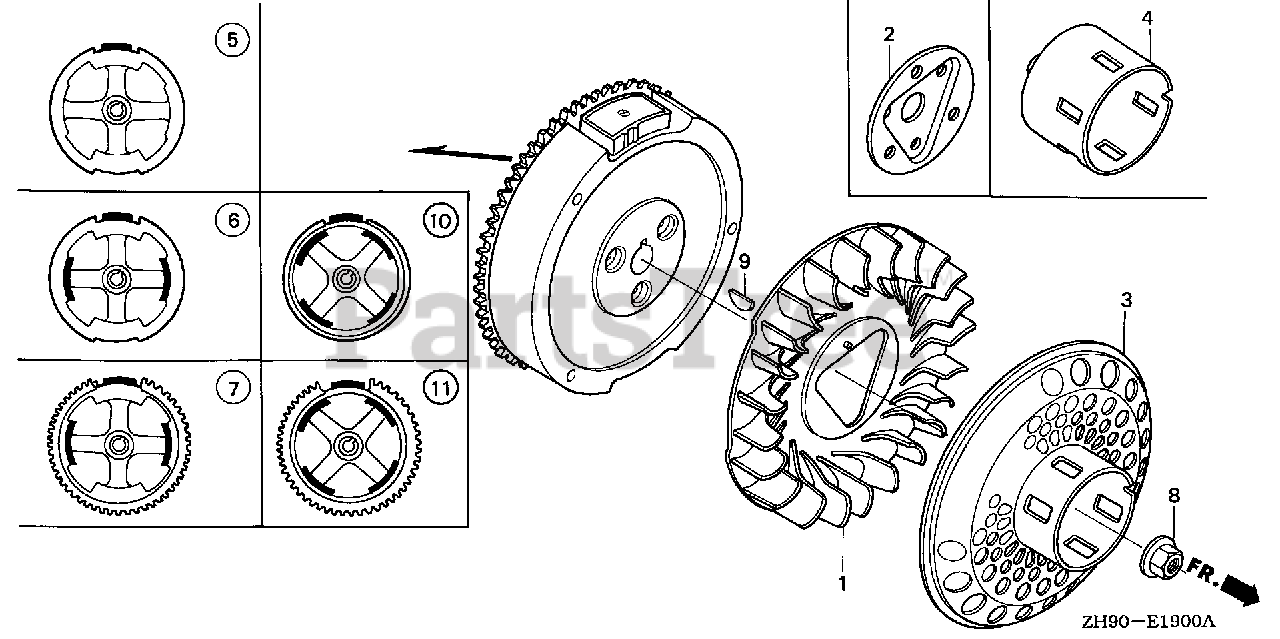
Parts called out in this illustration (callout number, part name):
1	FAN, COOLING
3	PULLEY, STARTER (SCREEN GRID)
8	NUT, SPECIAL (16MM)
9	KEY, SPECIAL WOODRUFF (25X18)
